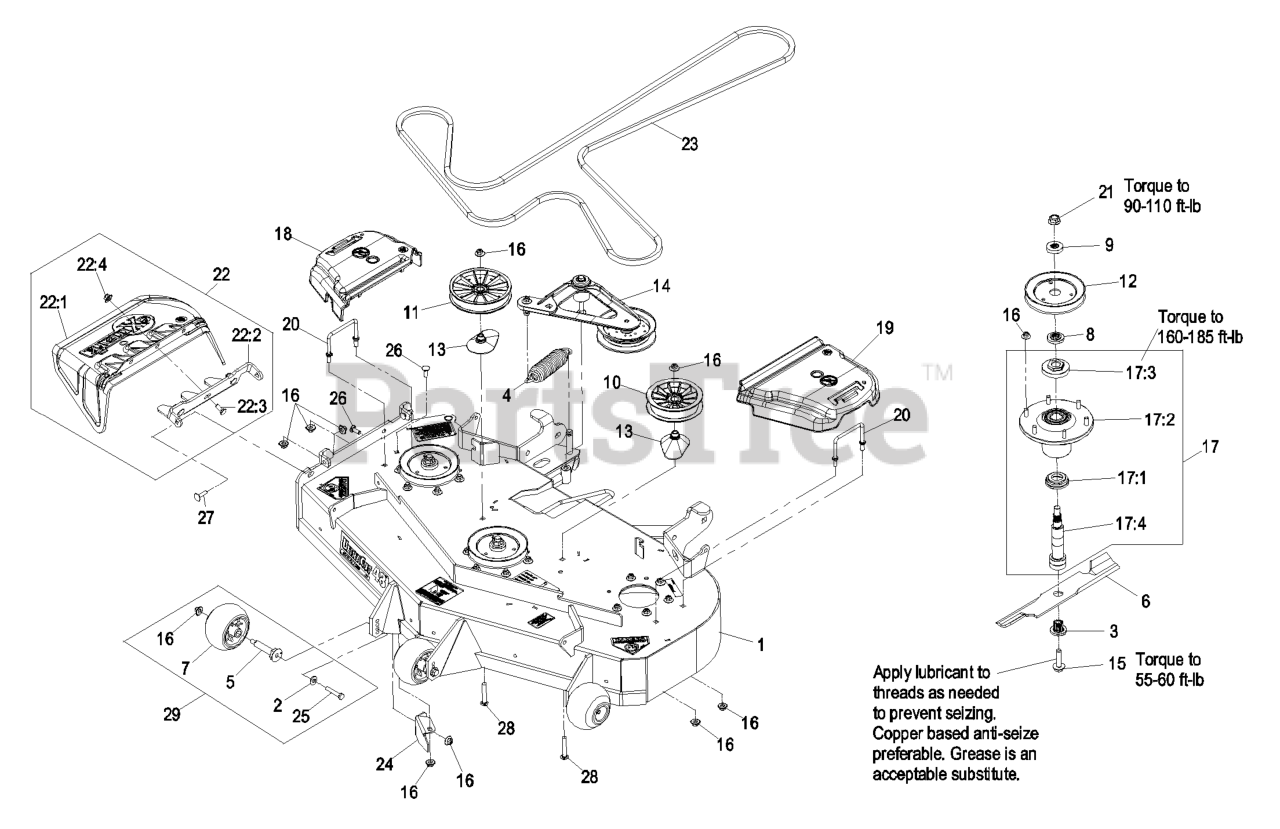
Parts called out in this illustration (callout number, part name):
1	ASM,DECK W/DECALS 48
2	WASHER-BELLEVILLE
3	BUSHING,SPLINED
7	ROLLER-SCALP, ANTI
8	SPACER,SPLINED STEPPED
9	SPACER,SPLINED
10	PULLEY,IDLER 5"
11	PULLEY,IDLER 6"
12	SHEAVE,BLADE DRIVE 5.90
13	SPACER-PULLEY
15	SCREW,SEMS 1/2-20 X 2.19
16	Nut-Nyloc 3/8-16 Flg
17	ASM,SPINDLE HOUSING
17:1	GUARD,BOTTOM
17:2	ASM,CUTTER HOUSING
17:3	NUT, SPINDLE 7/8-14
17:4	SPINDLE,DOUBLE SPLINE
18	COVER-BELT, RH
19	COVER-BELT, LH
20	WIREFORM-COVER
21	NUT-FLANGE, CENTERLOCK
22	ASM,DISCHARGE CHUTE
22:1	CHUTE,DISCHARGE
22:2	BRACKET,DISCHARGE CHUTE
22:3	SCREW-CARR
22:4	Nut-Nyloc 3/8-16 Flg
23	BELT
24	BAFFLE,DISCHARGE
25	SCREW-HH
26	SCREW-CARR
27	Bolt-Carriage 3/8-16 X 1 1/4
28	SCREW-CARR
30	Asm, Deck Complete 486
